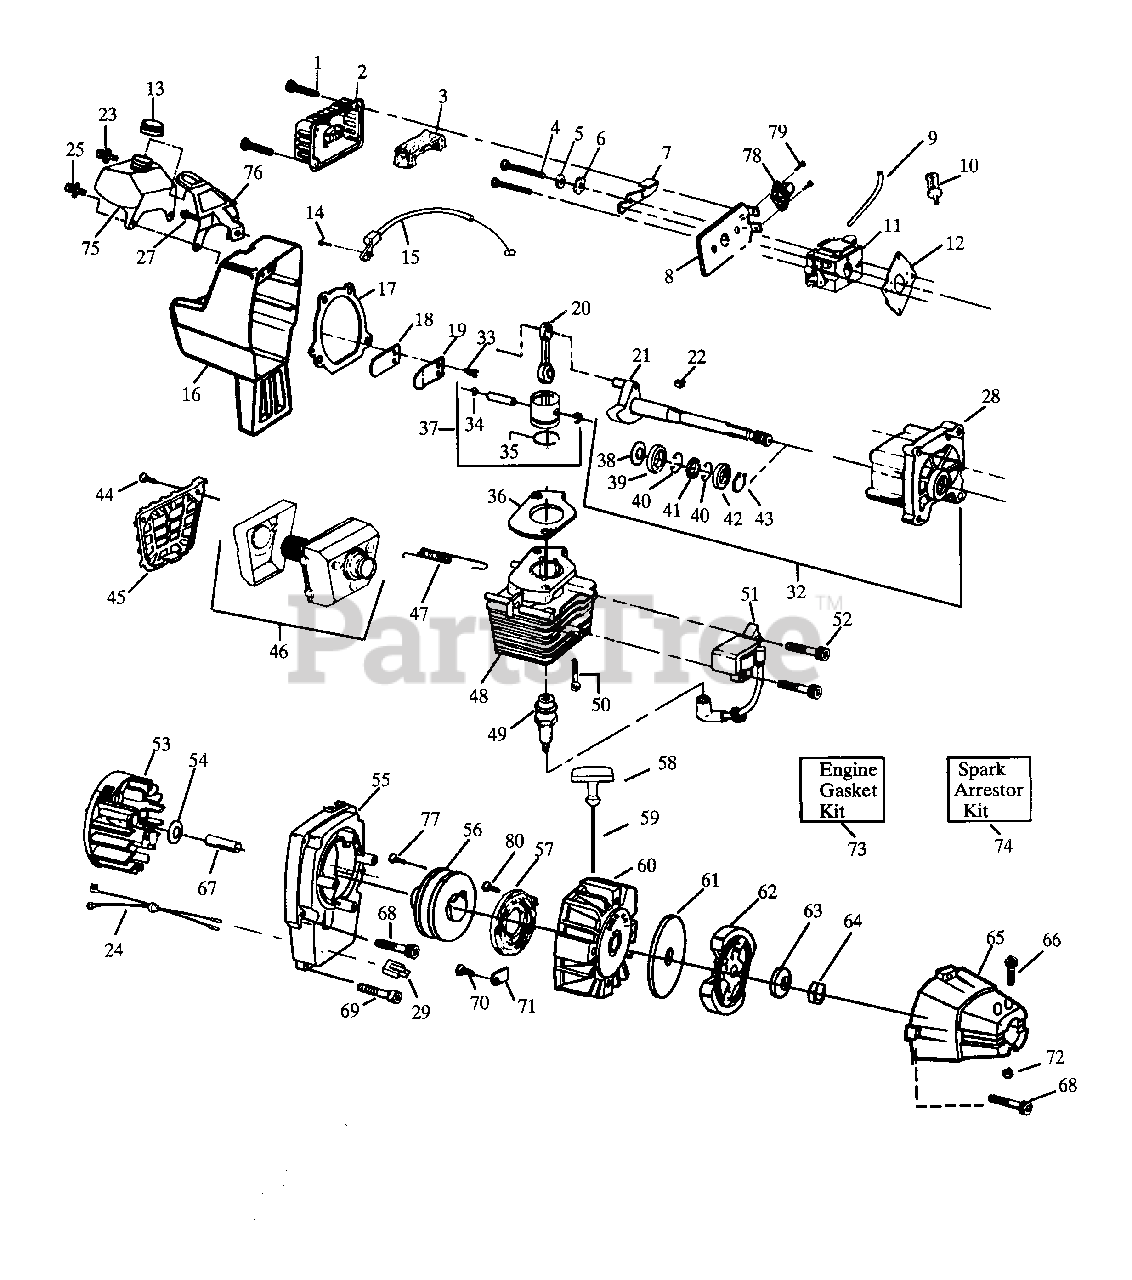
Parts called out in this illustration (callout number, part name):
2	Air Filter Cover
3	Air Filter
6	Wave Washer
7	Choke Shutter
8	Air Filter Plate
9	Fuel Line, Fuel Line
9	Fuel Line, Return Line
10	Fuel Pick-up Ass'y.
11	Carburetor (WT-298A) w/ Limiter Caps
12	Carburetor Gasket
13	Fuel Cap Ass'y.
15	Throttle Cable Ass'y
17	Crankcase/Shroud Gasket
19	Reed Stop
20	Connecting Rod Ass'y. (Incl. Bearings)
21	Crankshaft Ass'y. See Service Ref. 1
22	Flywheel Key
24	Leadwire/Grommet Ass'y.
27	Screw
28	Crankcase Ass'y. (Incl. 39-42)
29	Connector-Male
32	Crankcase & Crankshaft Ass'y (Incl. 21, 28 & 39-43)
34	Piston Pin Retainer
35	Piston Ring
36	Cylinder Gasket
37	Piston Kit (Incl. 34,35 & pin)
39	Inner Bearing
40	Retaining Ring
41	Crankshaft Seal
42	Outer Bearing
43	Crankshaft Retaining Ring
45	Muffler Guard
46	Muffler Kit
47	Muffler Attachment Spring
48	Cylinder
49	Spark Plug, Type 1 (CJ-14)
49	Spark Plug, Type 2 (RCJ-8Y)
51	Ignition Module Kit
52	Screw
53	Flywheel Ass'y.
55	Fan Housing
56	Starter Pulley Kit (Incl. 77)
57	Starter Spring
58	Starter Handle
59	Rope Kit
60	Pulley Housing Ass'y.
61	Clutch Washer
62	Clutch Ass'y. Kit
65	Clutch Housing
71	Retainer
73	Engine Gasket Kit (Inc. 12,36,17)
74	Spark Arrestor Kit
75	Fuel Tank Ass'y.
76	Fuel Tank Mtg. Bracket
77	Screw (Incl. in Starter Pulley Kit)
78	Primer Bulb Ass'y.
79	Screw-Primer
80	Screw-Starter Spring Type 2
